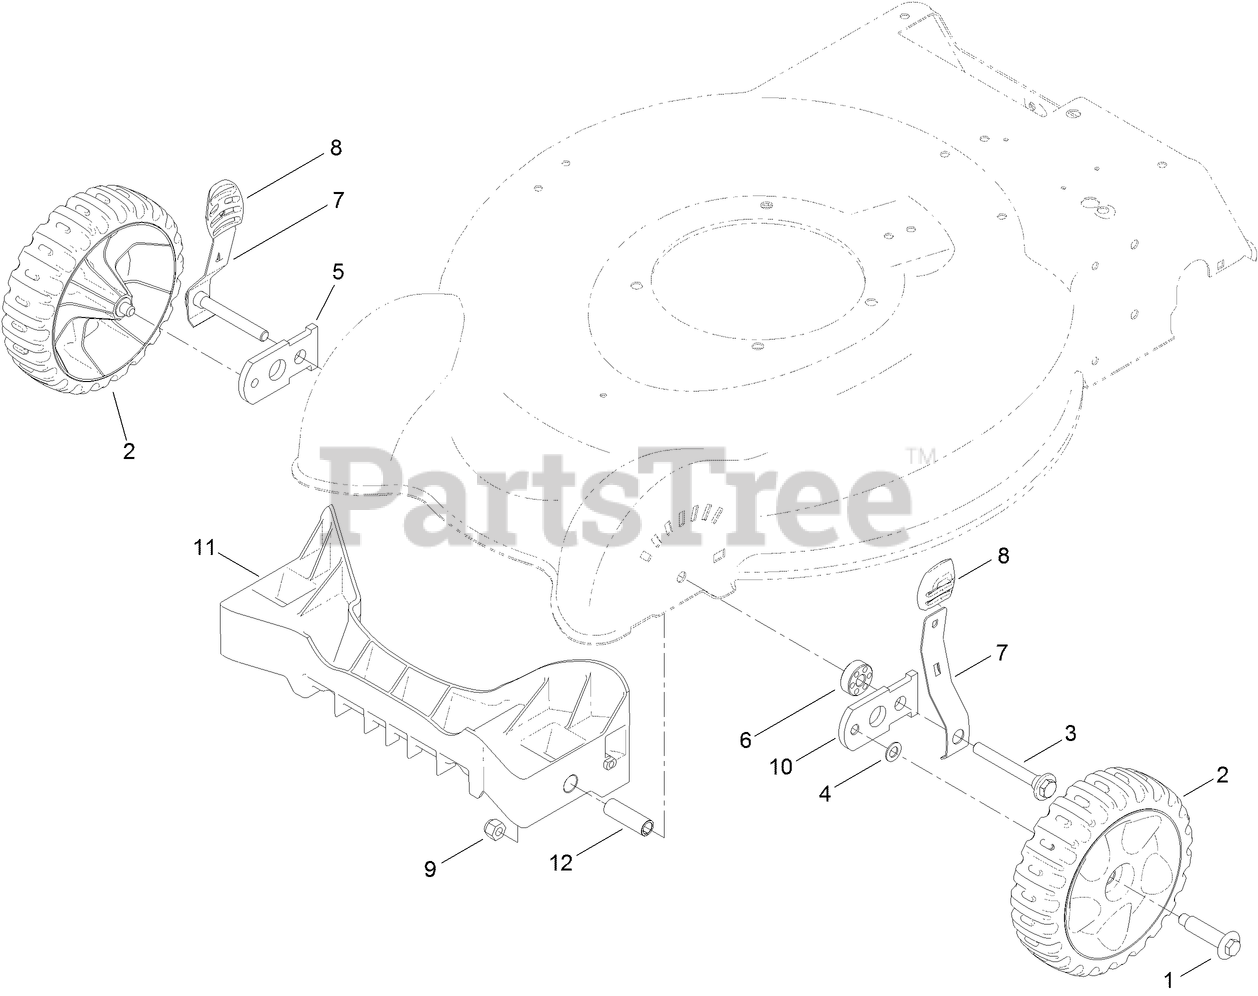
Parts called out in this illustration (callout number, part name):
1	BOLT-SHOULDER
2	7 INCH WHEEL AND TIRE ASM
3	BOLT-SHOULDER
4	WASHER
5	ARM-PIVOT, RH
6	SPACER-ARM, PIVOT
7	ARM-SPRING, FRONT
8	KNOB-LEVER, HOC
9	NUT-LOCK, NI
10	ARM-PIVOT, LH
11	BAFFLE-FRONT, RWD (CE)
12	SPACER-BAFFLE, FRONT
